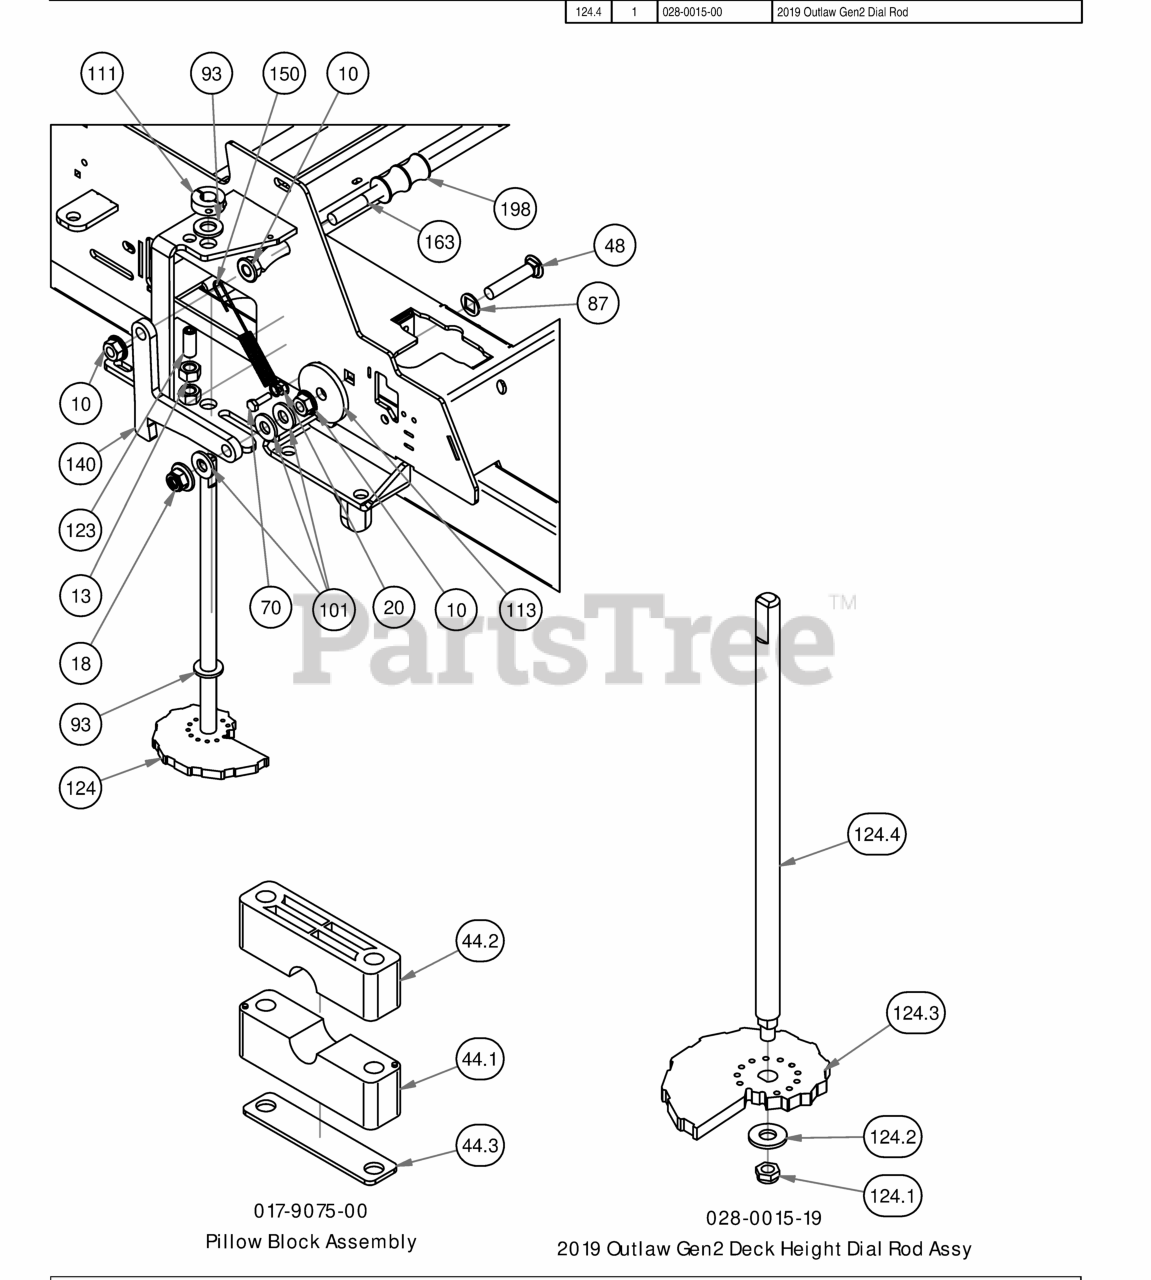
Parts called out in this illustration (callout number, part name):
10	1/2" Flange Nut
13	1/2" Hex Nut
18	1/2-13 Nylon Flange Nut
20	1/4-20 Hex Flange Nuts Zinc w/Serrations
44.1	Two Piece Pillow Block (Male)
44.2	Two Piece Pillow Block (Female)
44.3	Two Piece Pillow Block Strap
48	1/2 x 2-1/2 Carriage Bolt
70	1/4-20 x 1-1/4 GR 5 Hex Bolt
87	.517 Square Hole Round Washer
93	.630 ID Plastic Washer
101	.505 Nylon Spacer
111	5/8" Split Collar
113	MZ Deck Idler Spacer
123	Dial Rod Plunger
124	2019 Outlaw Gen2 Deck Height Dial Rod Assy
124.1	3/8-24 Nylon Insert jam locknut
124.2	3/8" Flat Washer
124.3	2019 Deck Height Cam
124.4	2019 Outlaw Gen2 Dial Rod
140	2019 Outlaw Deck Travel Lock
150	Brake Spring
163	Seat Bracket Pin
198	Travel Lock Rubber Grip
